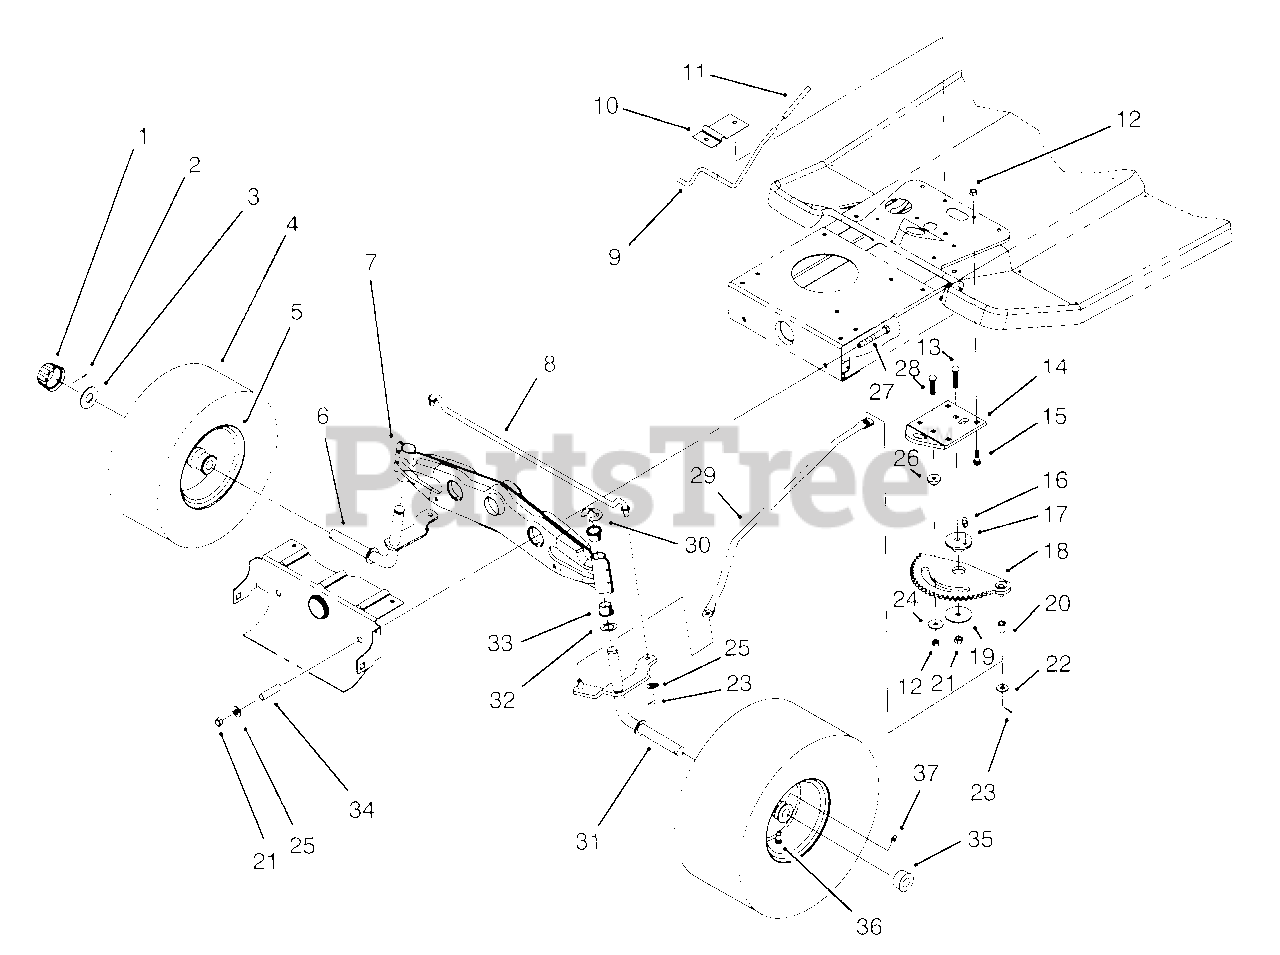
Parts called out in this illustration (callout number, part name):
1	Nut-Lock
2	Washer-Flat
3	Bushing-Sliding
4	Screw-Hex Hd. Cap
5	Wheel-Steering(Incl Ref. #6)
6	Insert-Steering Wheel
9	Shaft-Steering
10	Bushing-Flange
11	Washer-Thrust
